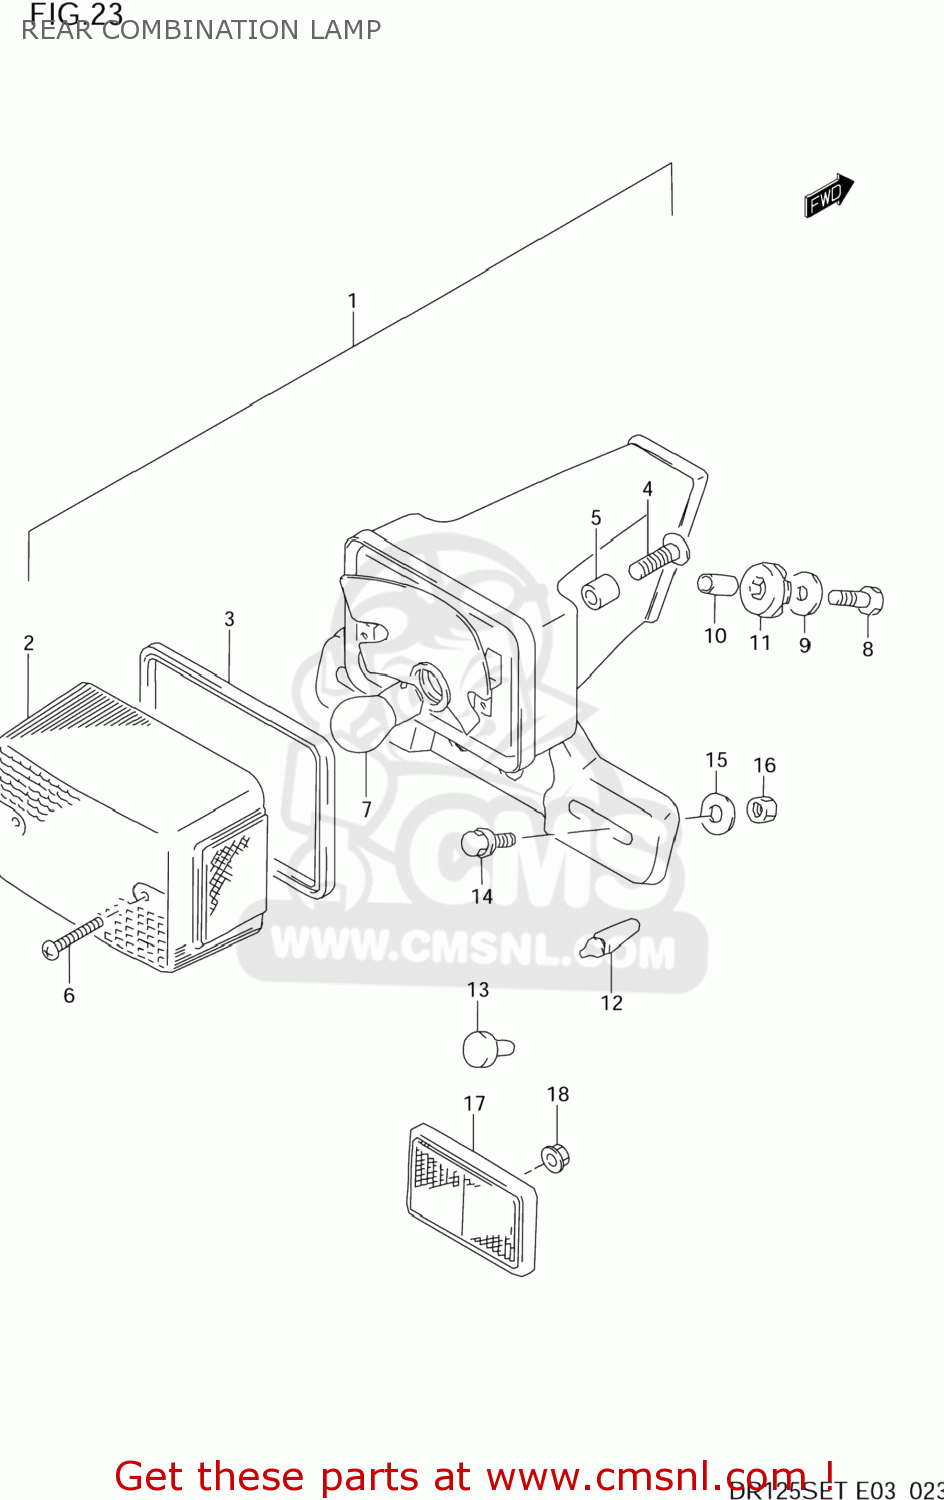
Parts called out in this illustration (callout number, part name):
1	LAMP ASSY,RR COMBINATION
2	LENS
3	GASKET,LENS (NAS)
4	SCREW(6X25)
5	SPACER
6	SCREW(4X45)
7	BULB(12V21/5W)
8	BOLT
9	WASHER
10	SPACER (6.8X10X13)
11	CUSHION
12	CUSHION
13	CUSHION
14	BOLT
15	WASHER
16	NUT 6MM
17	RR ASSY,RR
18	NUT
